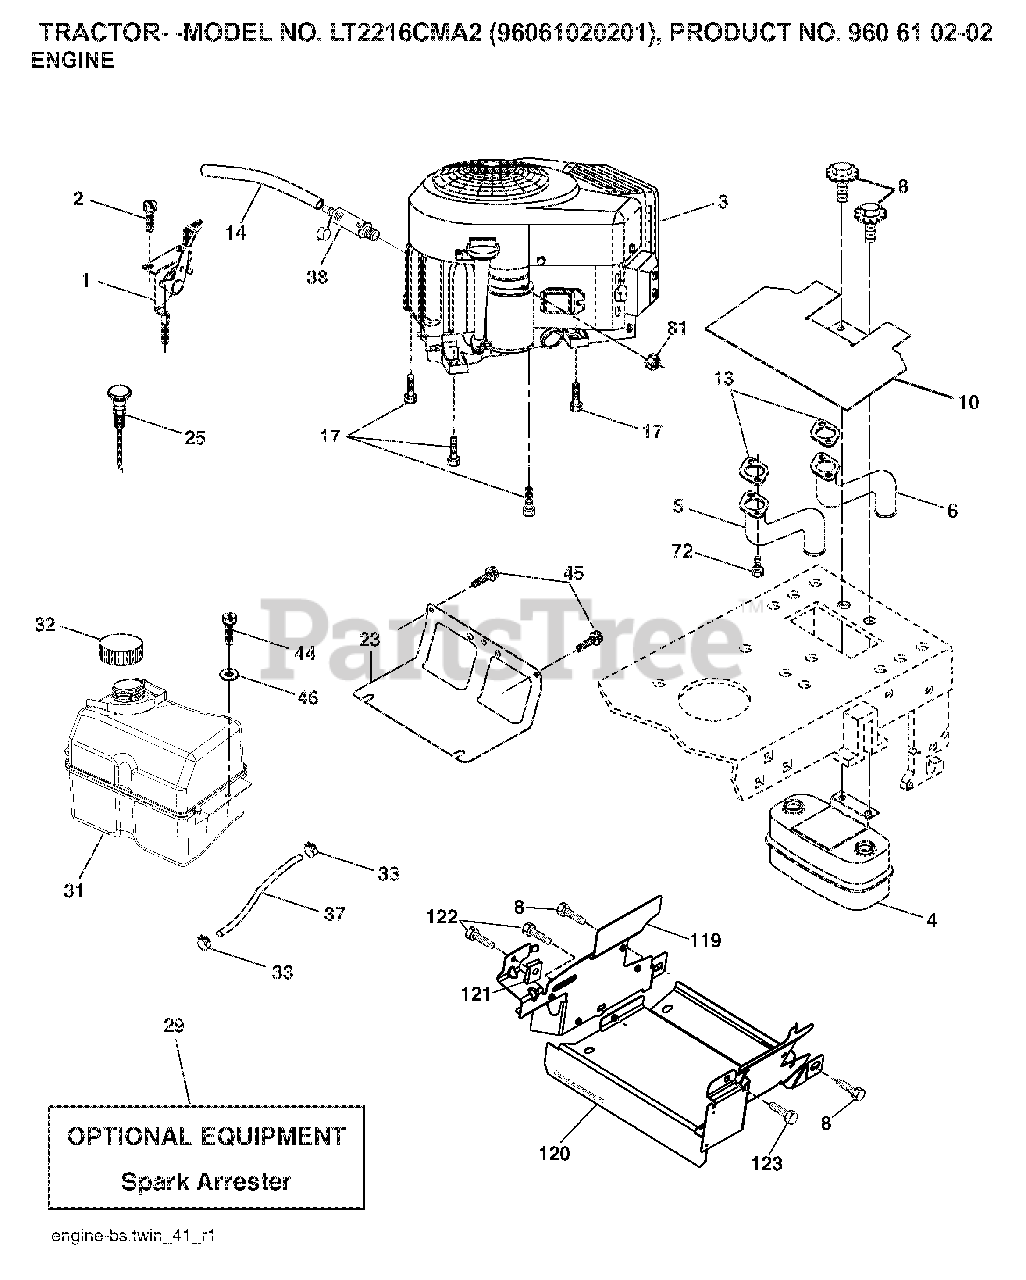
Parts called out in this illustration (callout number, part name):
1	CONTROL, THROTTLE
2	SCREW
4	MUFFLER.TWIN.CYL.LOW.TONE
5	TUBE MANIFOLD LH
6	EXHAUST TUBE RH
8	BOLT, 5/16-18 X 1 3/4
10	RP SHIELD HEAT MUFFLER
13	GASKET.MUFFLER
14	TUBE, DRAIN OIL ASM.
17	SCREW.3/8-16
23	SHEILD.BROWNING.DBR.GUARD
29	ARRESTER SPARK (OPTIONAL)
31	TANK FUEL
32	FUEL CAP
33	HOSE CLAMP
37	LINE.FUEL.20
38	PLUG DRAIN OIL EASY
44	SCREW HEXWSHR 1/4-20X3/4
45	SCREW, 3/8-16X3/4
72	SCREW.SOCKET.HEAD.5/16-18
81	NUT
122	SCREW.1/4-20X5/8
123	SCREW, 5/16-18 X 1/2
